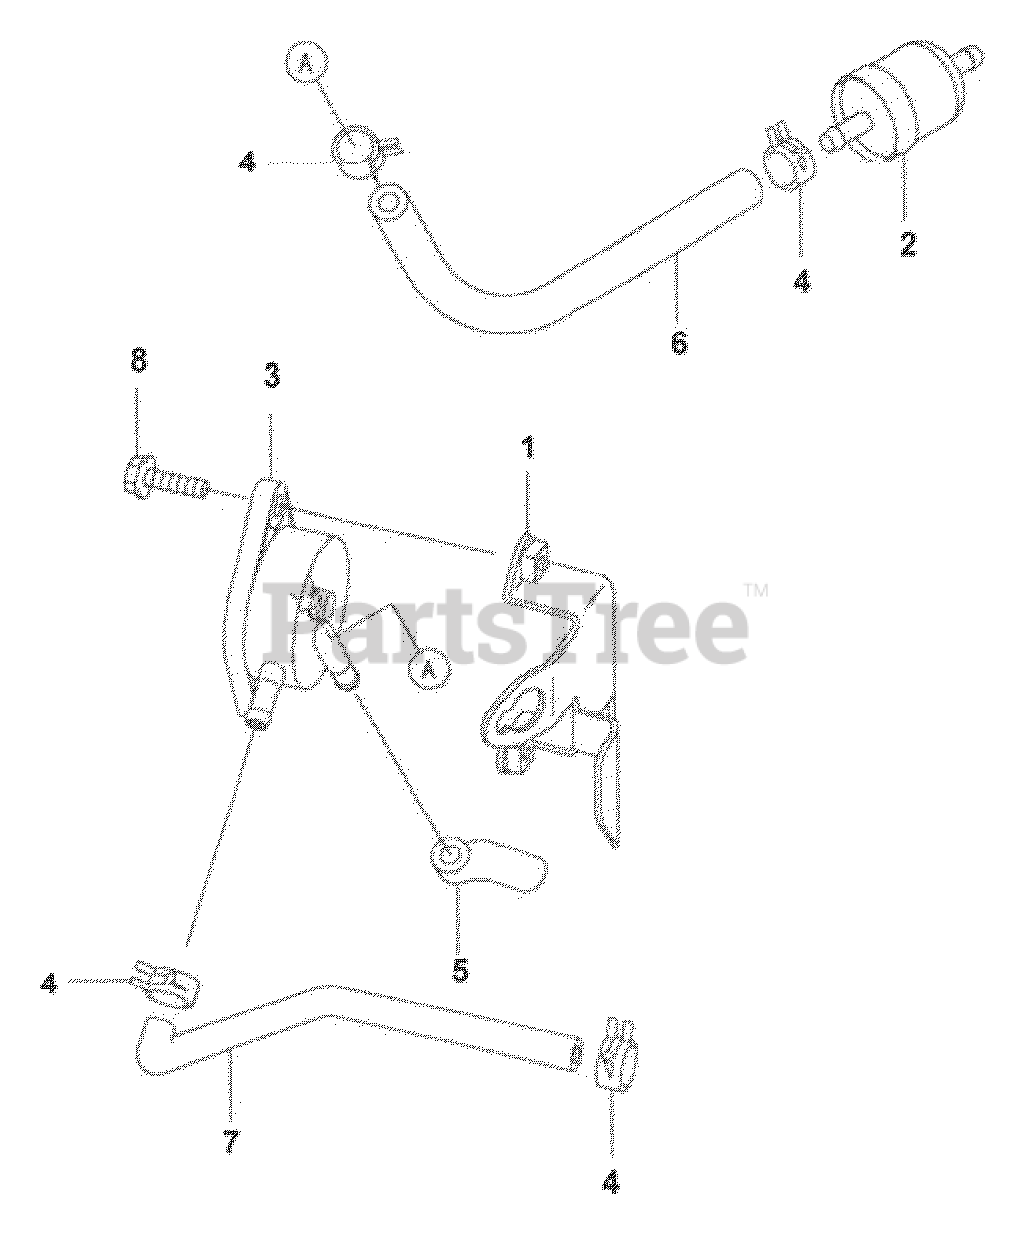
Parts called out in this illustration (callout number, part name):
1	Bracket
2	Fuel Filter
3	Fuel Pump
4	Clamp
8	Flange Bolt
